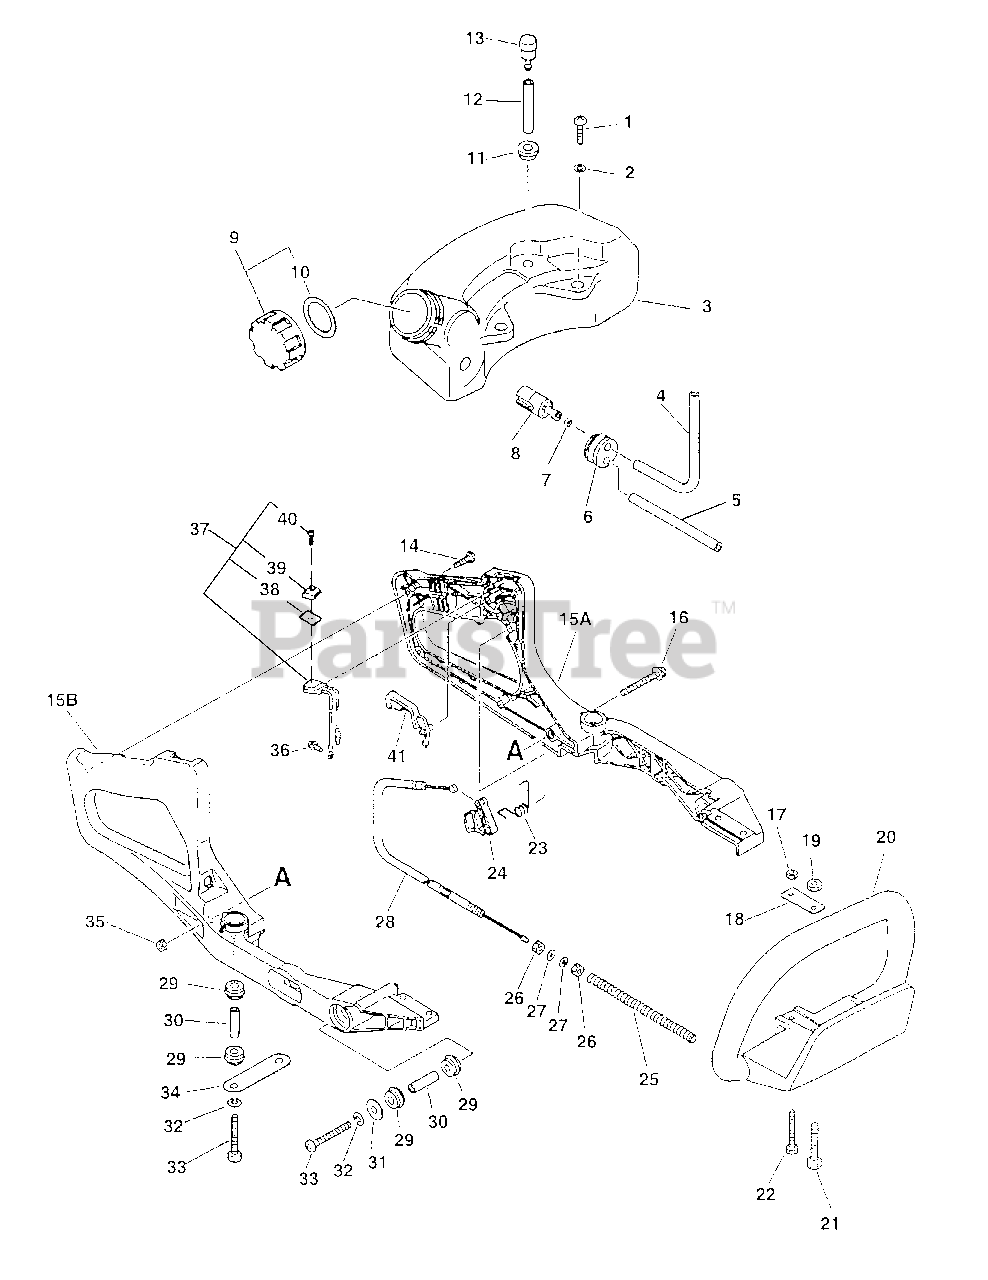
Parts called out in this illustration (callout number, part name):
1	SCREW - 5X16
2	WASHER - 5
3	TANK, FUEL
4	PIPE, FUEL - CORRUGATED
5	PIPE - 3X5X180 -- BLACK
5	PIPE, FUEL - CORRUGATED
6	GROMMET
7	CLIP - 6
8	FILTER, FUEL
9	CAP ASSY
10	GASKET, CAP
11	GROMMET
12	PIPE - 3X6X35 -- BLACK
13	VENT, FUEL TANK
14	SCREW - 4X25
15A	HANDLE, REAR - LEFT
15B	HANDLE, REAR - RIGHT
16	SCREW - 5X64
19	LOCKNUT - 6
20	HANDLE - FRONT
21	BOLT - 6X32
22	BOLT - 5X35
23	SPRING, LOCKOUT LEVER
24	TRIGGER, THROTTLE
27	WASHER - 6
28	CABLE, THROTTLE
30	SPACER
32	LOCKWASHER - 5
33	SCREW - 5X40
34	PLATE
36	SCREW - 5X10
37	IGNITION SWITCH ASSY
38	COVER, SWITCH - STOP
39	KNOB, SWITCH - ORANGE
40	SCREW - 3X10
41	LOCKOUT, THROTTLE
